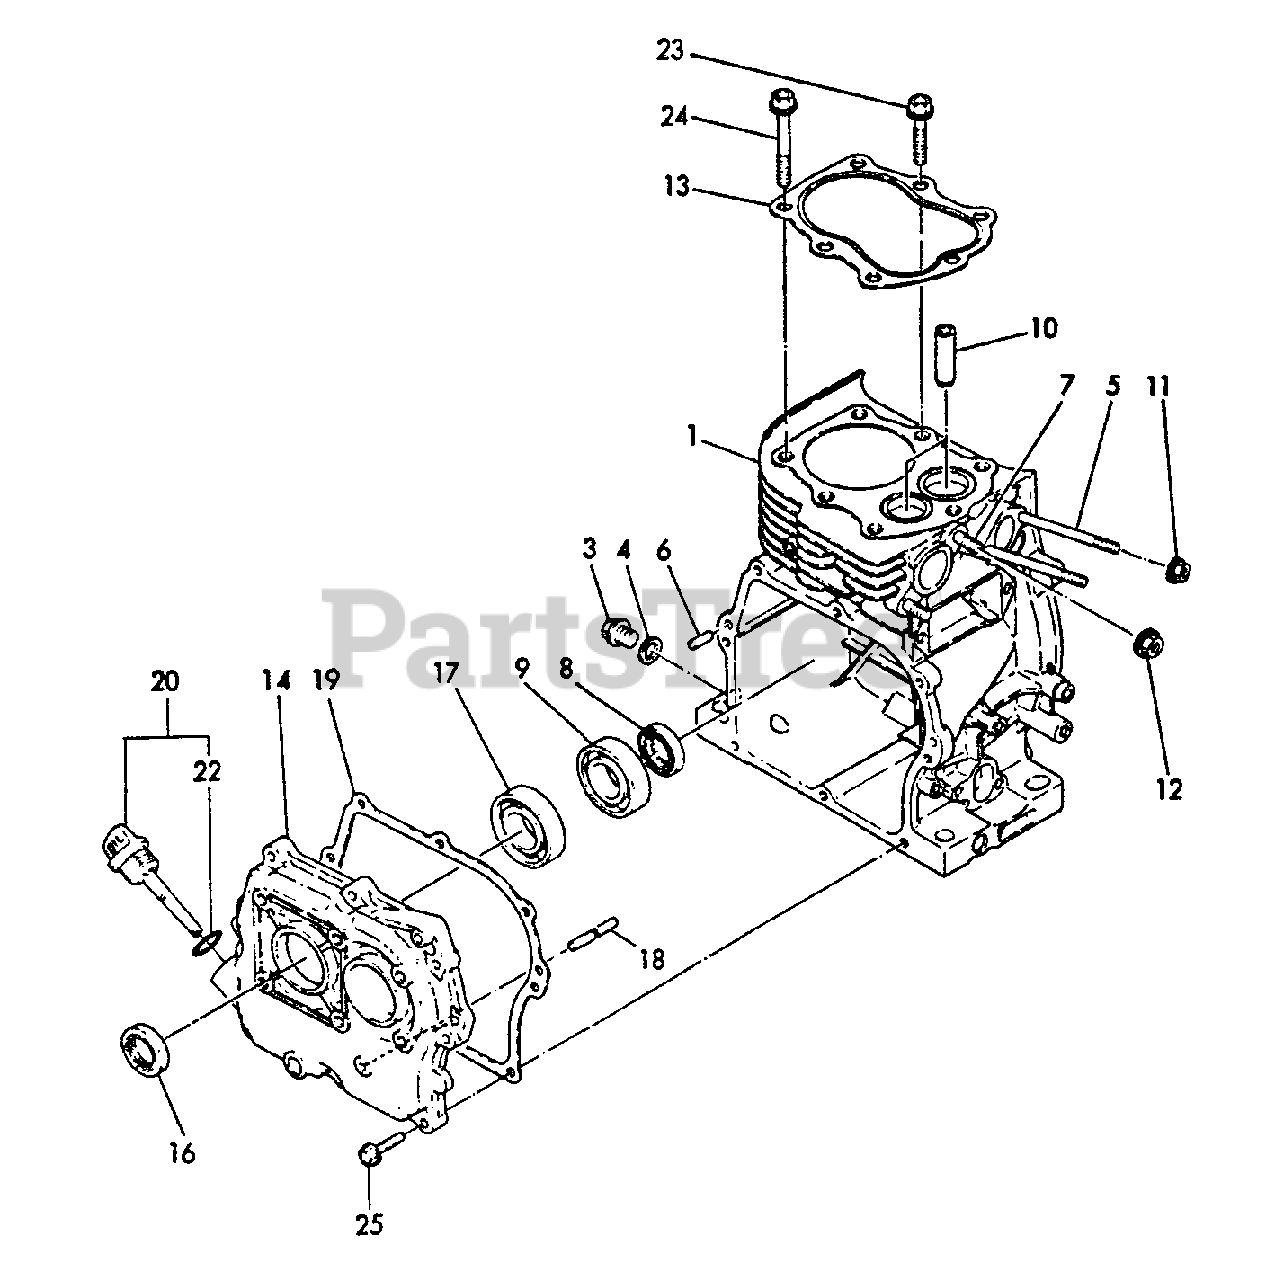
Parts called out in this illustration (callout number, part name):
1	CYLINDER BLOCK SET
3	PLUG, DRAIN
4	GASKET
5	BOLT - 6×70
6	PARALLEL PIN 6×16
7	STUD - 8×18 -- PLATED
8	SEAL, OIL
9	BEARING, BALL
10	GUIDE, VALVE - EXHAUST
11	U-NUT M6
12	U-NUT M8
13	GASKET, CYLINDER
14	SIDE COVER ASSY
16	SEAL, OIL
17	BEARING, BALL
18	SHAFT, GOVERNOR
19	GASKET, SIDE COVER
20	CAP ASSY
22	O-RING 1A P-18.0
23	BOLT - 8×39
24	BOLT - 8×65
25	BOLT - 6×30
